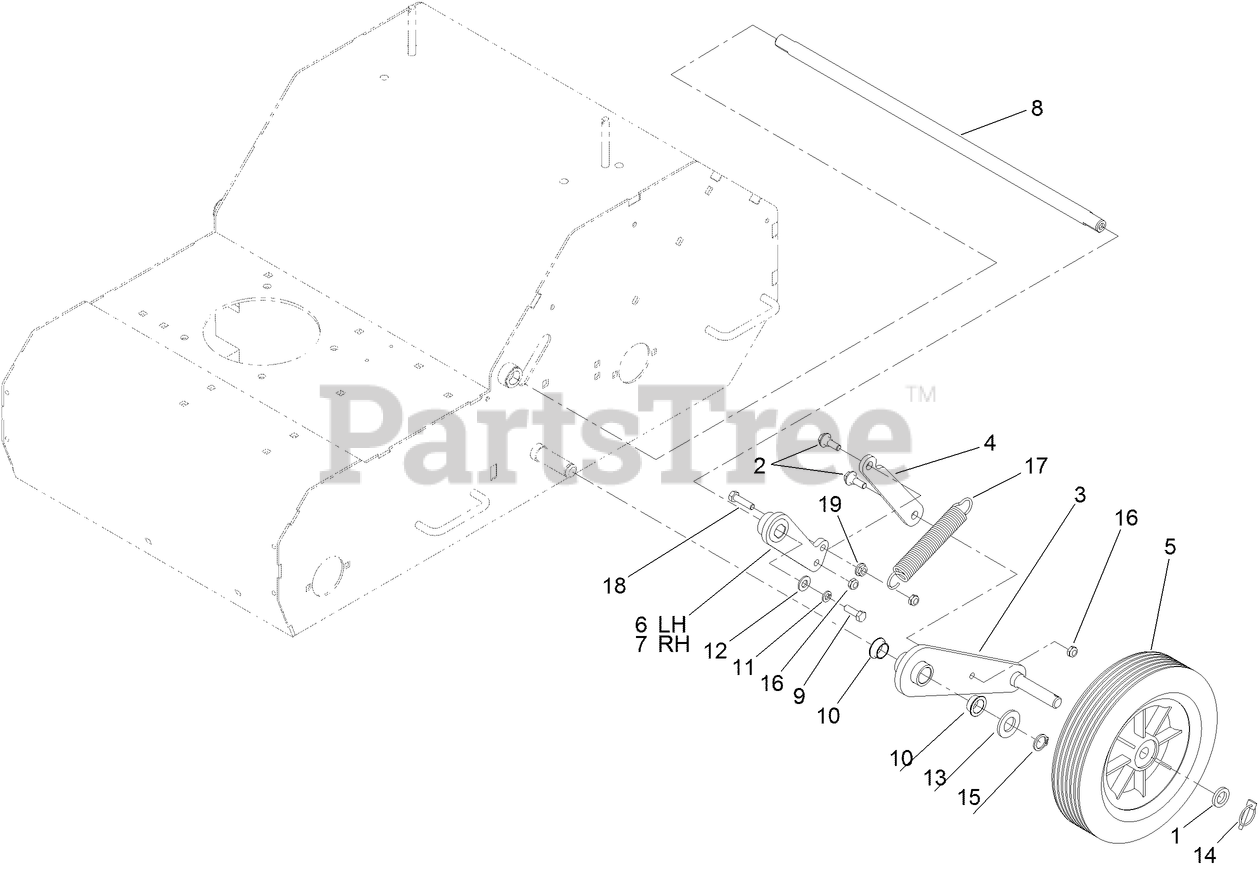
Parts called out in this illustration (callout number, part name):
1	SPACER-BEARING
2	SCREW-SHOULDER
3	ARM-WHEEL
4	LINK-CONNECTING
5	WHEEL-TRANSPORT 10"
6	HUB-LIFT, LH
7	HUB-LIFT, RH
8	SHAFT-PIVOT
9	SCREW-HH
10	BUSHING-BRONZE
11	WASHER-LOCK
12	WASHER-FLAT
13	WASHER-FLAT
14	PIN-KLIK
15	RING-RETAINING
16	NUT-LOCK, NI
17	SPRING-EXTENSION
18	SCREW-HH
19	NUT-HF
